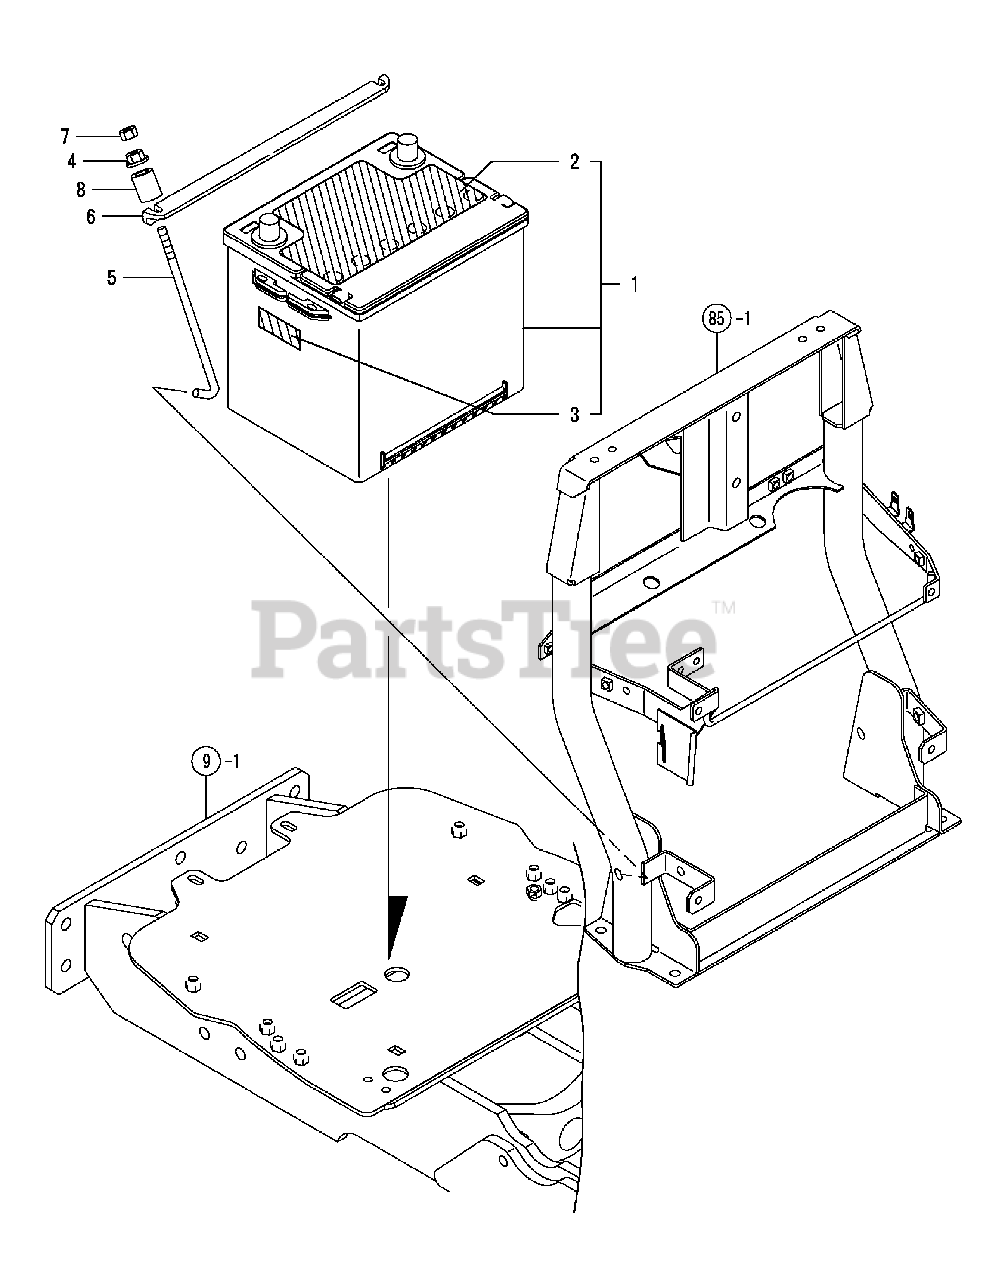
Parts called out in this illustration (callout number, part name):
1	BATTERY,26R,ASSY
2	LABEL,BATTERY
3	LABEL,CA,65,WARN
4	NUT W/WASHER 8
5	ROD, BATTERY CLAMP
